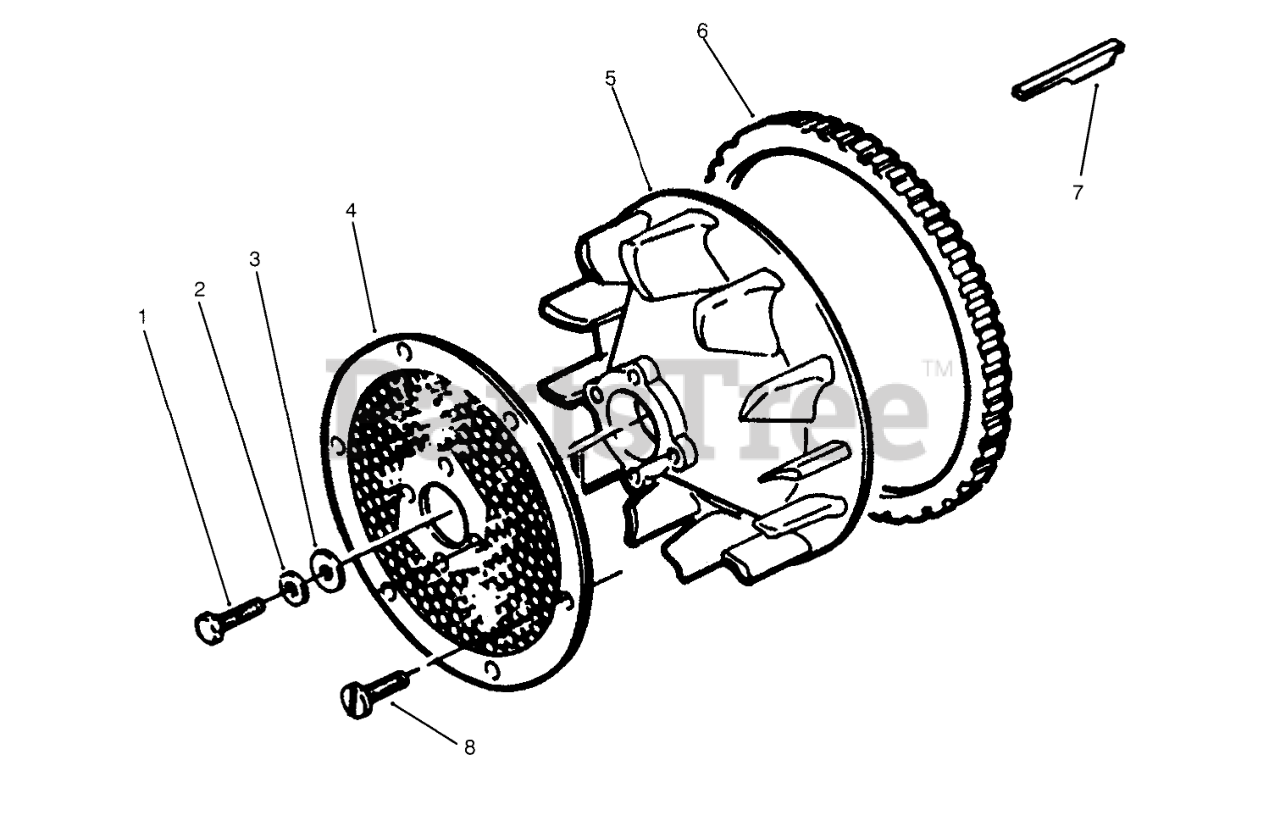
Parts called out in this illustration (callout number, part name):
1	SCREW
2	WASHER-FLAT
3	WASHER-FLAT
4	Screen
5	Flywheel (Incl. Ref. #6)
7	KEY-FLYWHEEL
8	LOCK SCREW
